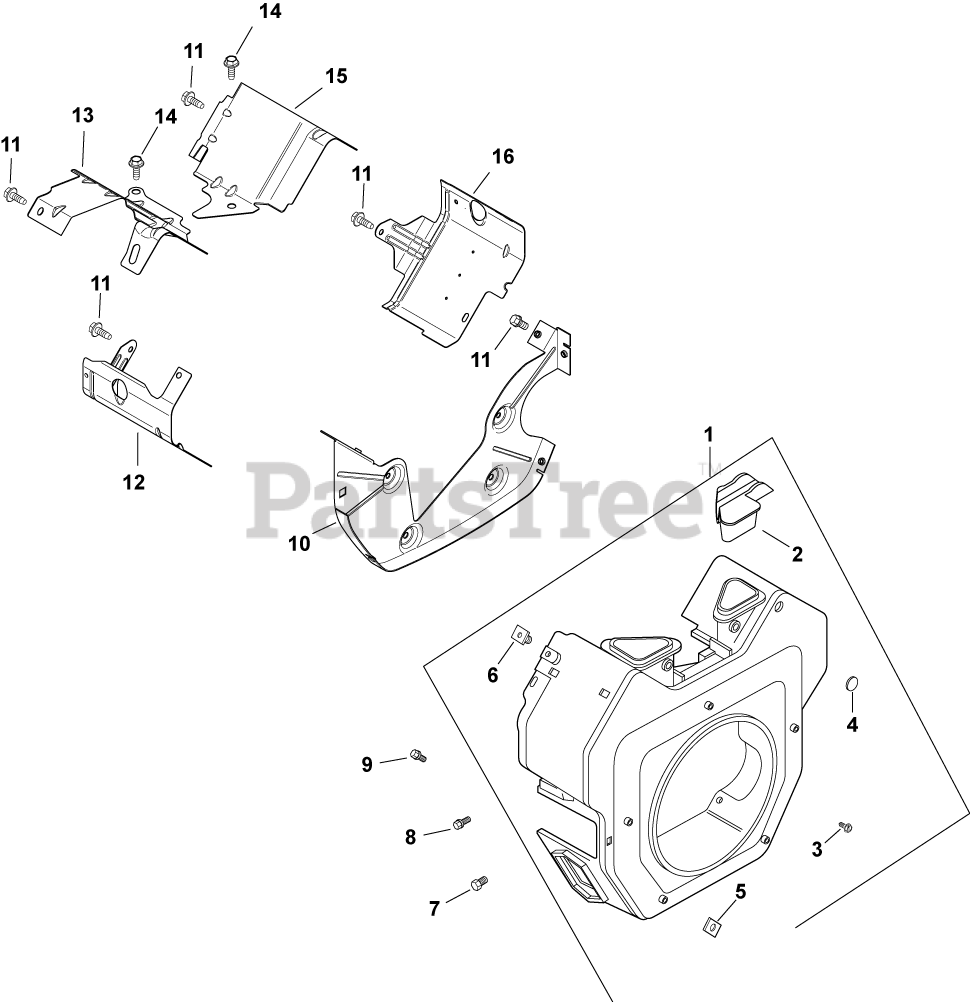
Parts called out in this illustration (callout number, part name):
1	KIT, BLOWER HOUSING ASSEMBLY - USE 24 027 491-S
2	COVER, BLOWER HOUSING-USE 24 096 119-S
3	SCREW, WSH HD TAP #8-18X1/2"
4	PLUG, BUTTON 9/16
5	NUT, PLASTIC (KM)-USE 25 100 37-S
6	NUT, PLASTIC
7	SCREW,FLG THD FRM M6X1.0X16-(#25086397S)
8	SCREW, HVY FLG M5X.8X16
9	SCREW,FLG THD FRM M5X0.8X16-(#25086398S)
10	PLATE, BACKING-USE 24 146 59-S
11	SCREW, FLG THD FRM M5X.8X20-(#25086399S)
12	BAFFLE, VALLEY #2 SIDE-USE 24 063 94-S
13	BAFFLE, VALLEY (CH)-USE 24 063 93-S
14	SCREW, HVY FLG M5X.8X10
15	BAFFLE, CYL BARREL - #2 SIDE-DISC.
16	CYL BARREL #1 SIDE
